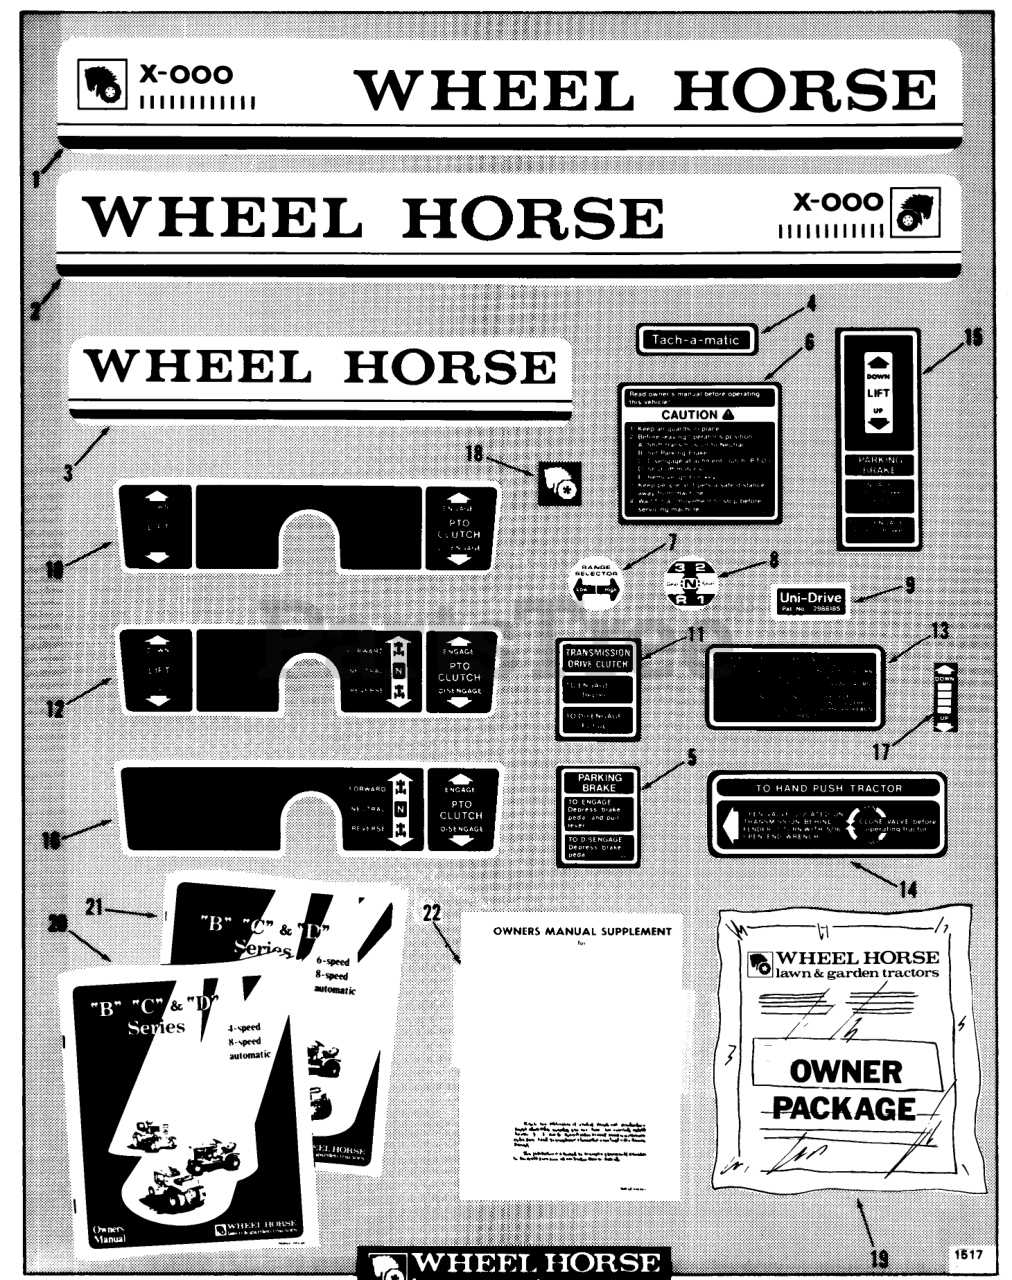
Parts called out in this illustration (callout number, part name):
1	Decal LH C-111 Only Automatic
1	Decal LH C-121 Automatic
1	Decal LH C-141 Automatic
1	Decal LH C-161 Automatic
1	Decal LH C-161 Twin Automatic
1	Decal LH C-111 Only 8-Speed
1	Decal LH C-81 8-Speed
1	Decal LH C-101 8-Speed
1	Decal LH C-121 8-Speed
1	Decal LH C-141 8-Speed
1	Decal LH C-161 8-Speed
1	Decal LH C-161 Twin 8-Speed
2	Decal RH C-111 Only Automatic
2	Decal RH C-121 Automatic
2	Decal RH C-141 Automatic
2	Decal RH C-161 Automatic
2	Decal RH C-161 Twin Automatic
2	Decal RH C-81 8-Speed
2	Decal RH C-101 8-Speed
2	Decal RH C-111 8-Speed
2	Decal RH C-121 8-Speed
2	Decal RH C-141 8-Speed
2	Decal RH C-161 8-Speed
2	Speed Nut
3	Decal-Rear
4	DECAL-TACHAMATIC
5	DECAL-PARKING BRAKE
6	DECAL-CAUTION
7	DECAL HI-LO
8	DECAL-SHIFT
9	Decal-Uni Drive
10	Decal-Control Housing
11	Decal-Transmission Clutch
12	Decal-Control Housing C-121 Only
13	Decal-Maintenance
14	Decal-Push Valve
15	Decal-Parking Brake & Lift
16	Decal-Control Housing C-141, C-161, C-161 Twin Only
17	Decal-Height Control
18	DECAL-LOGO
19	Loose Parts Package C-101, C-121 Only
19	Loose Parts Package C-111 Only
19	Loose Parts Package C-141, C-161 Only
19	Loose Parts Package C-161 Twin Only
19	Loose Parts Package C-81 Only
20	Owner-s Manual
21	Owner-s Manual
22	Supplement-Tractor Owner-s Manual C-161 Twin Only
22	Supplement-Tractor Owner-s Manual C-111 Only
